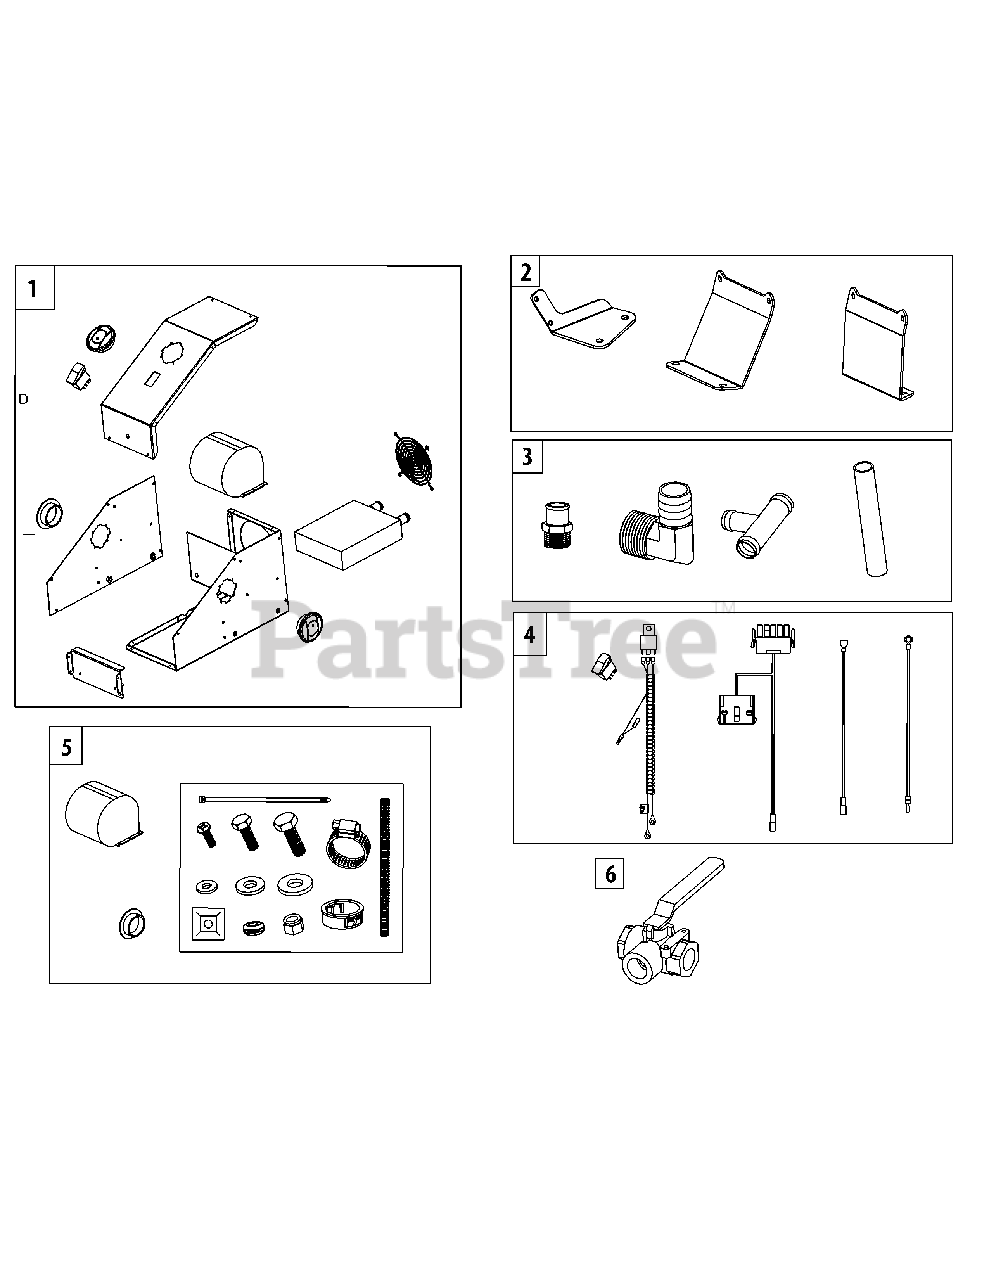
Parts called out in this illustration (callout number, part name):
1	TUCK-AWAY HEATER - VOLUNTEER 20,000 BTU MEGA BURNER
2	MOUNTING BRACKET KIT HEATER VOLUNTEER
3	FITTINGS KIT HEATER VOLUNTEER
4	ELECTRICAL KIT HEATER VOLUNTEER
5	MISC PARTS KIT HEATER VOLUNTEER
6	3/4 NPT 3 WAY VALVE
